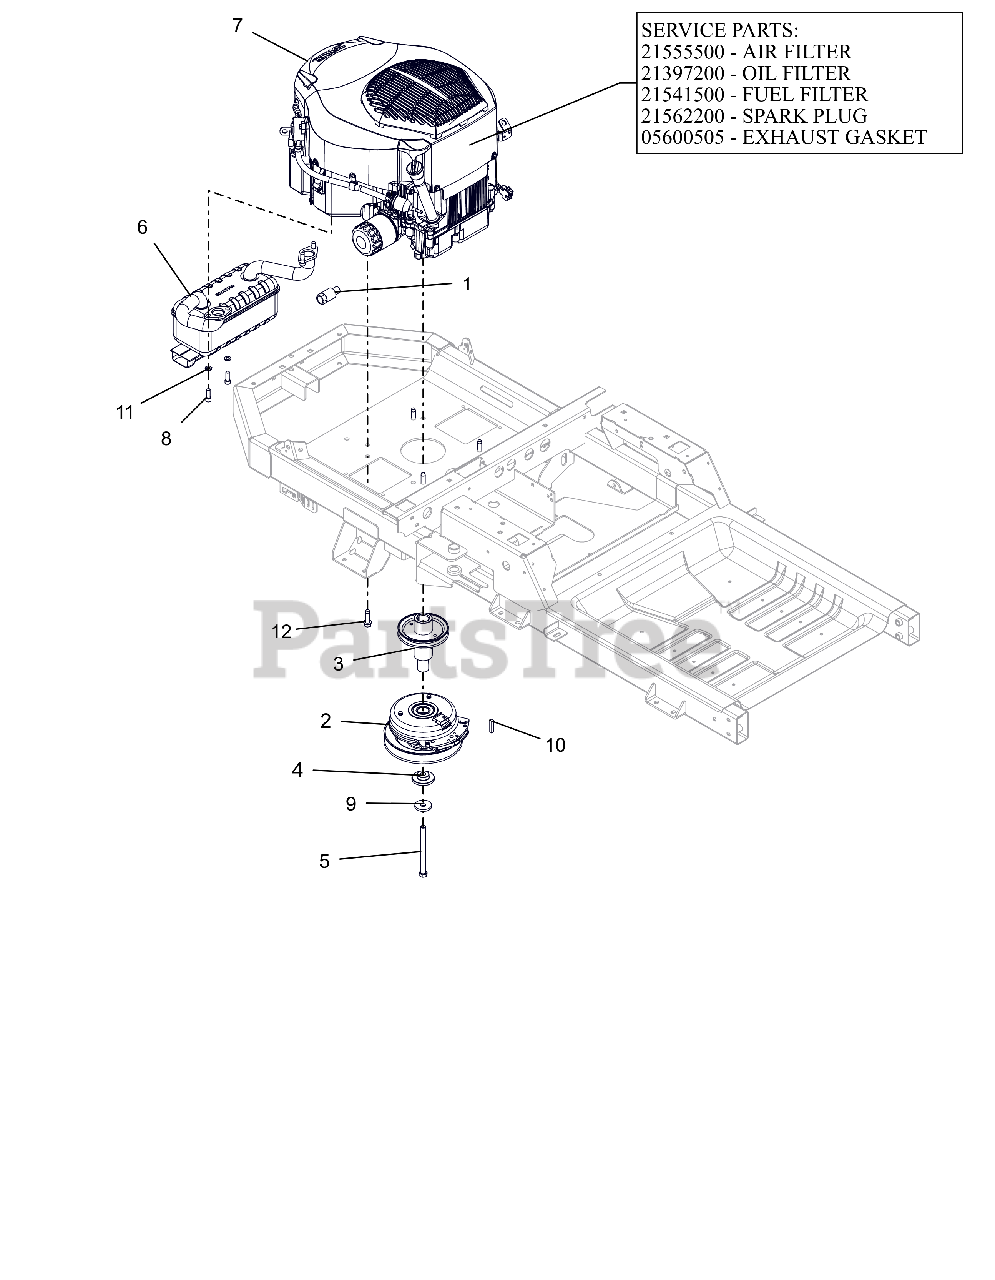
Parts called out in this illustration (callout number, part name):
1	DRAIN, OIL
2	CLUTCH,105FTLB MONOPOLE 6.83"
3	WLDMT, DRIVE SHEAVE (LG XL)CZC
4	BSHG-FLG .469X1.06X.574X2.0
5	BLT-HEX.438-20X5 GR8 YZ NYTORQ
6	MUFFLER, KOHLER
7	ENGINE, KOHLER TWIN - 25HP
7	AIR CLEANER, KOHLER
7	FILTER, OIL - KOH CV20
7	FILTER, FUEL
7	PLUG, SPARK (RFI)
7	GASKET, MUFFLER COURAGE TWIN
8	SCR-CAP .31-18X.88 S/HD G8 ZCC
9	WASHER, 7/16" SPRING DISK
10	KEY-SQ .25 X 1.25 X .25 SAE
11	WSHR,LK-REG .312X.078 ZCC
12	SCR,TAP .375-16X1.25HWH TR ZCC
